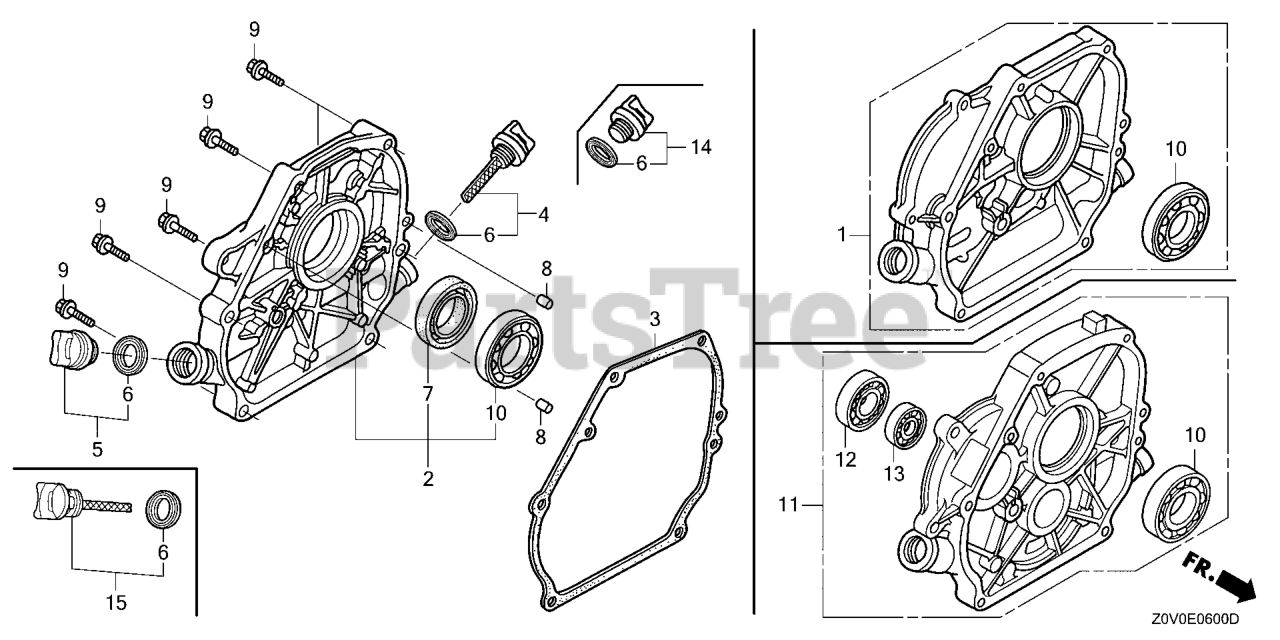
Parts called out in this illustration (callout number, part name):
2	COVER ASSY., CRANKCASE
3	GASKET, CASE COVER (NON-ASBESTOS)
4	CAP ASSY., OIL FILLER
5	CAP ASSY., OIL FILLER
6	GASKET, OIL FILLER CAP
7	OIL SEAL (25X41X6)
8	PIN A, DOWEL (8X14)
9	BOLT, FLANGE (8X32)
10	BEARING, RADIAL BALL (6205)
